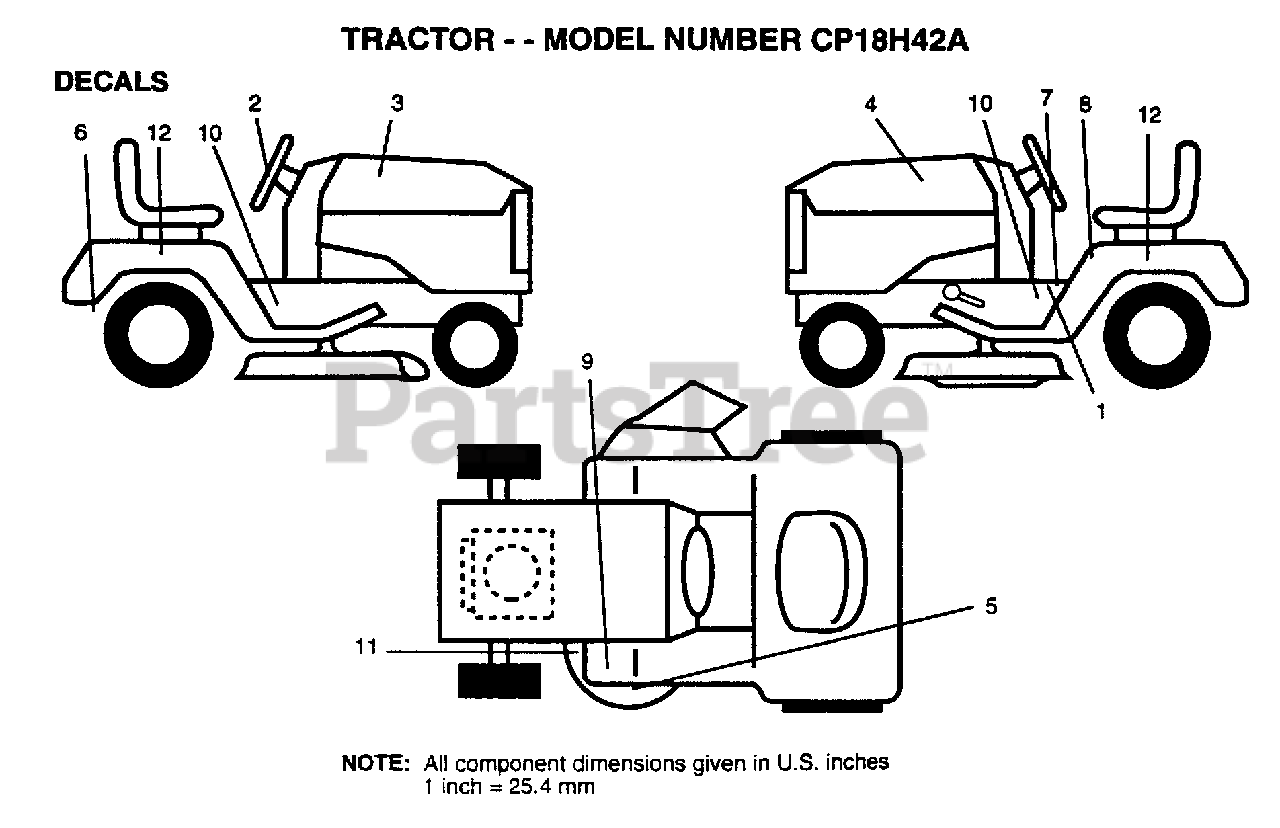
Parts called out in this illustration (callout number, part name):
3	DECAL.HD.CP18H42A
4	DECAL.HD.CP18H42A
6	DECAL DRAWBAR LH
7	DECAL SADLE HYDRO
8	DECAL
10	DECAL CHAS 42 HYD
11	DECAL
12	DECAL.FEND.QUICK.
